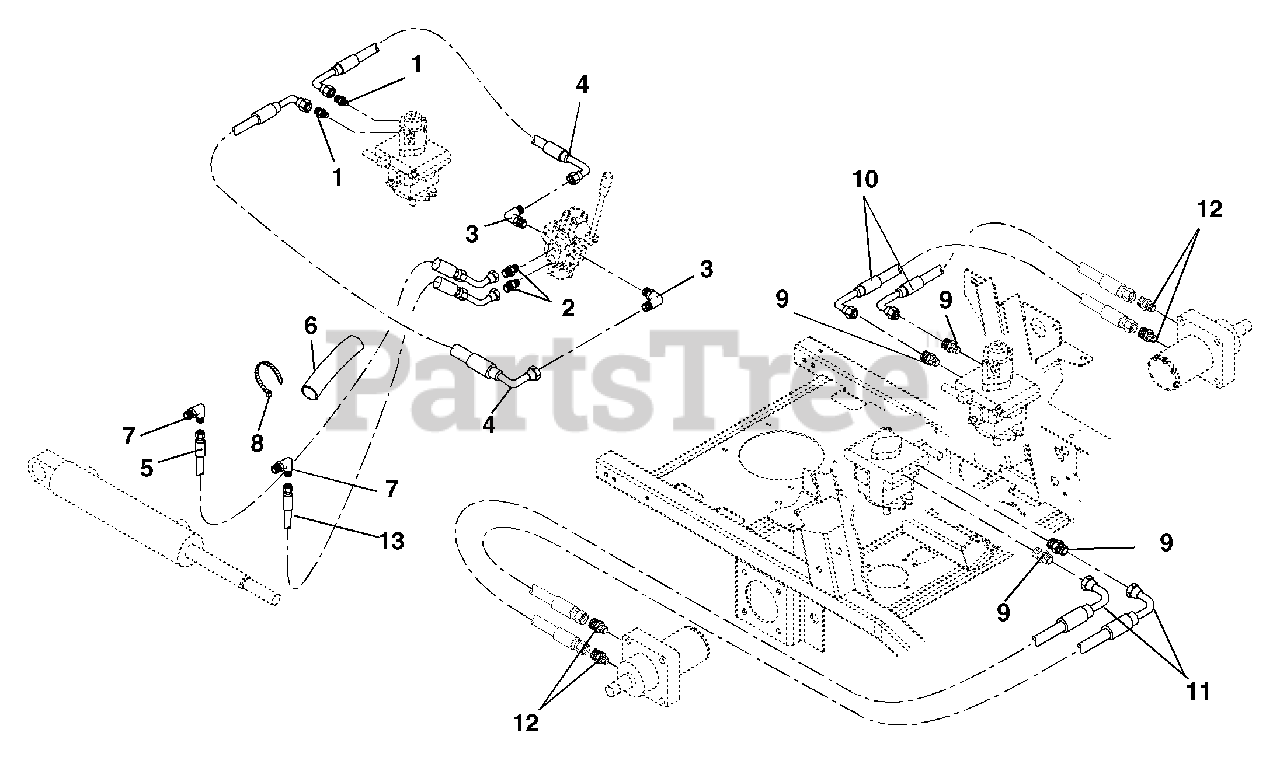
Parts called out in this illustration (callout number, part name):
1	Fitting, Hydraulic
2	Fitting, Hydraulic
3	Fitting, Hydraulic Elbow
4	Hose, Hydraulic
5	Hose, Hydraulic
6	Sleeve, Protective 24"
7	Fitting, Hydraulic Elbow
8	Cable Tie
9	Adapter, Hydraulic
10	Hose, Hydraulic
11	Hose, Hydraulic
12	Adapter, Hydraulic
13	Hose, Hydraulic
